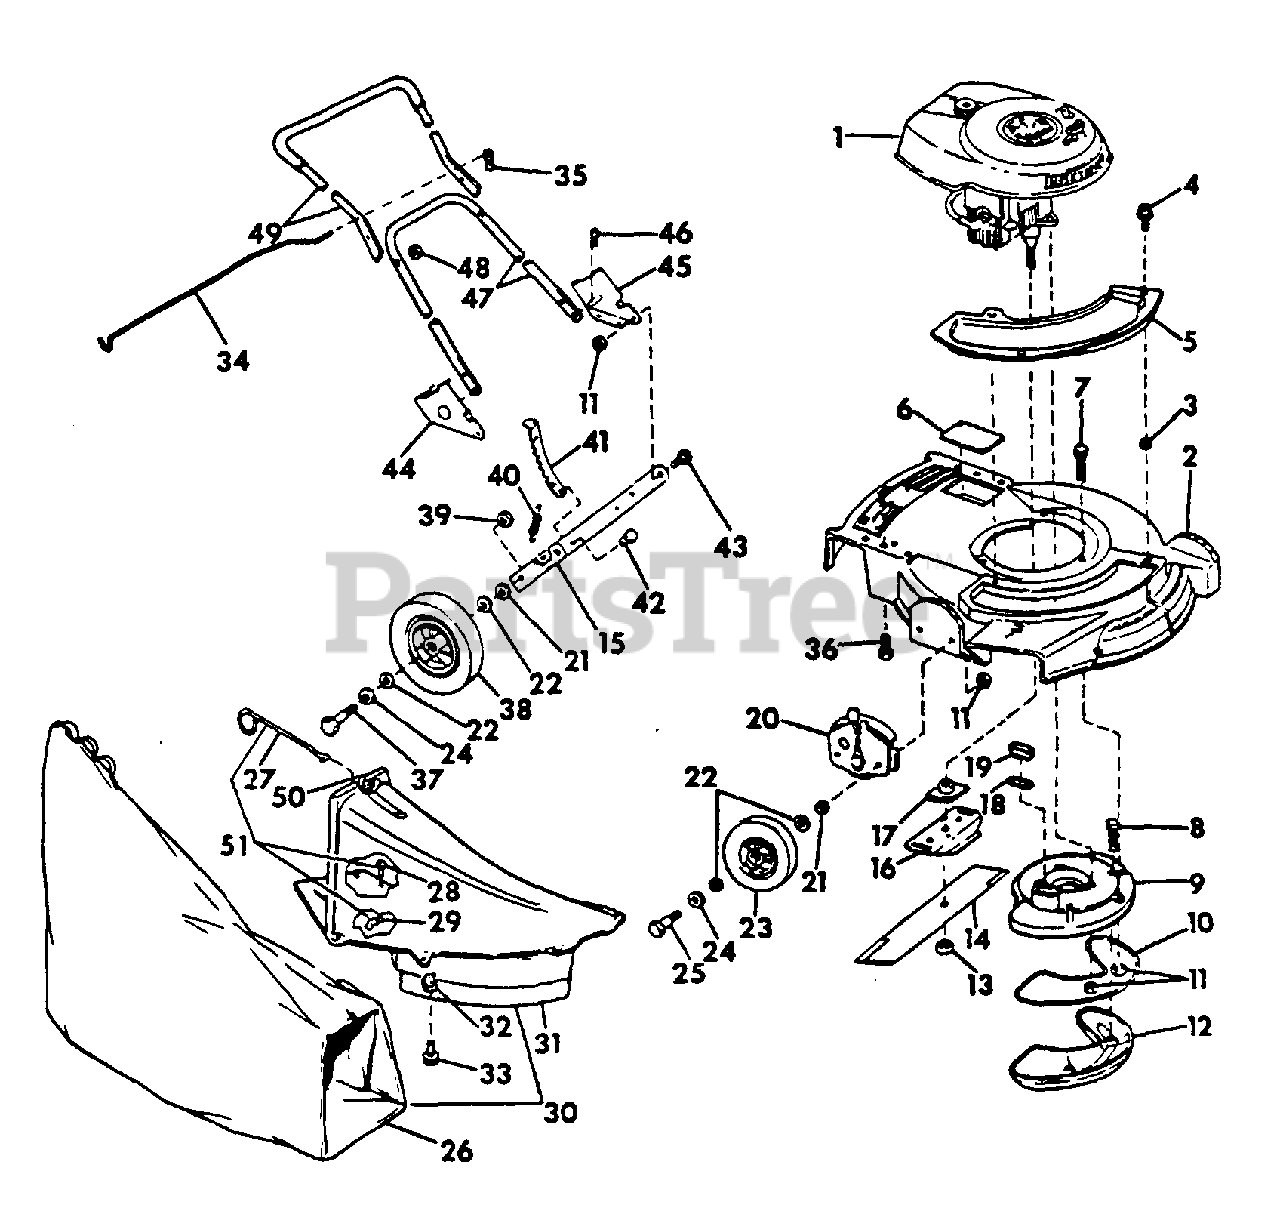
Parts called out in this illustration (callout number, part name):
1	ENGINE, IH
2	HOUSING ASSY, 21 IN.
3	NUT, GROMMET
4	SCREW, HEX-HD
5	COVER, CHUTE OPENING
6	COVER, POCKET
7	SCREW, MUFFLER PLATE TO HSG
8	SCREW, MUFFLER TO MUFFLER PLATE
9	PLATE W/SCREW, MUFFLER
10	GASKET, MUFFLER
14	BLADE, 21 IN.
16	STIFFENER, BLADE
17	COLLAR & PLATE
18	GASKET, EXHAUST
19	SLEEVE, EXHAUST GASKET
20	ADJUSTMENT, HEIGHT
22	WASHER, FELT
23	WHEEL & TIRE, 6 IN.
24	WASHER, WHEEL BOLT HD
25	BOLT, WHEEL FRT SHOULDER
27	GUARD, WHEEL
30	CHUTE ASSY
31	SKIRT ASSY CHUTE
34	ROD, GRASS BAR
36	SCREW, HANDLE BRACKET
37	BOLT, REAR WHEEL
38	WHEEL & TIRE, 8 IN.
39	NUT, REAR WHEEL BOLT
40	SPRING, HEIGHT ADJ
41	LEVER, HEIGHT ADJ REAR
44	BRACKET, HANDLE RH
45	BRACKET, HANDLE LH
47	HANDLE, BOTTOM
48	NUT, CENTERLOCK
49	HANDLE & GRIP, TOP
51	GUARD ASSY, WHEEL
